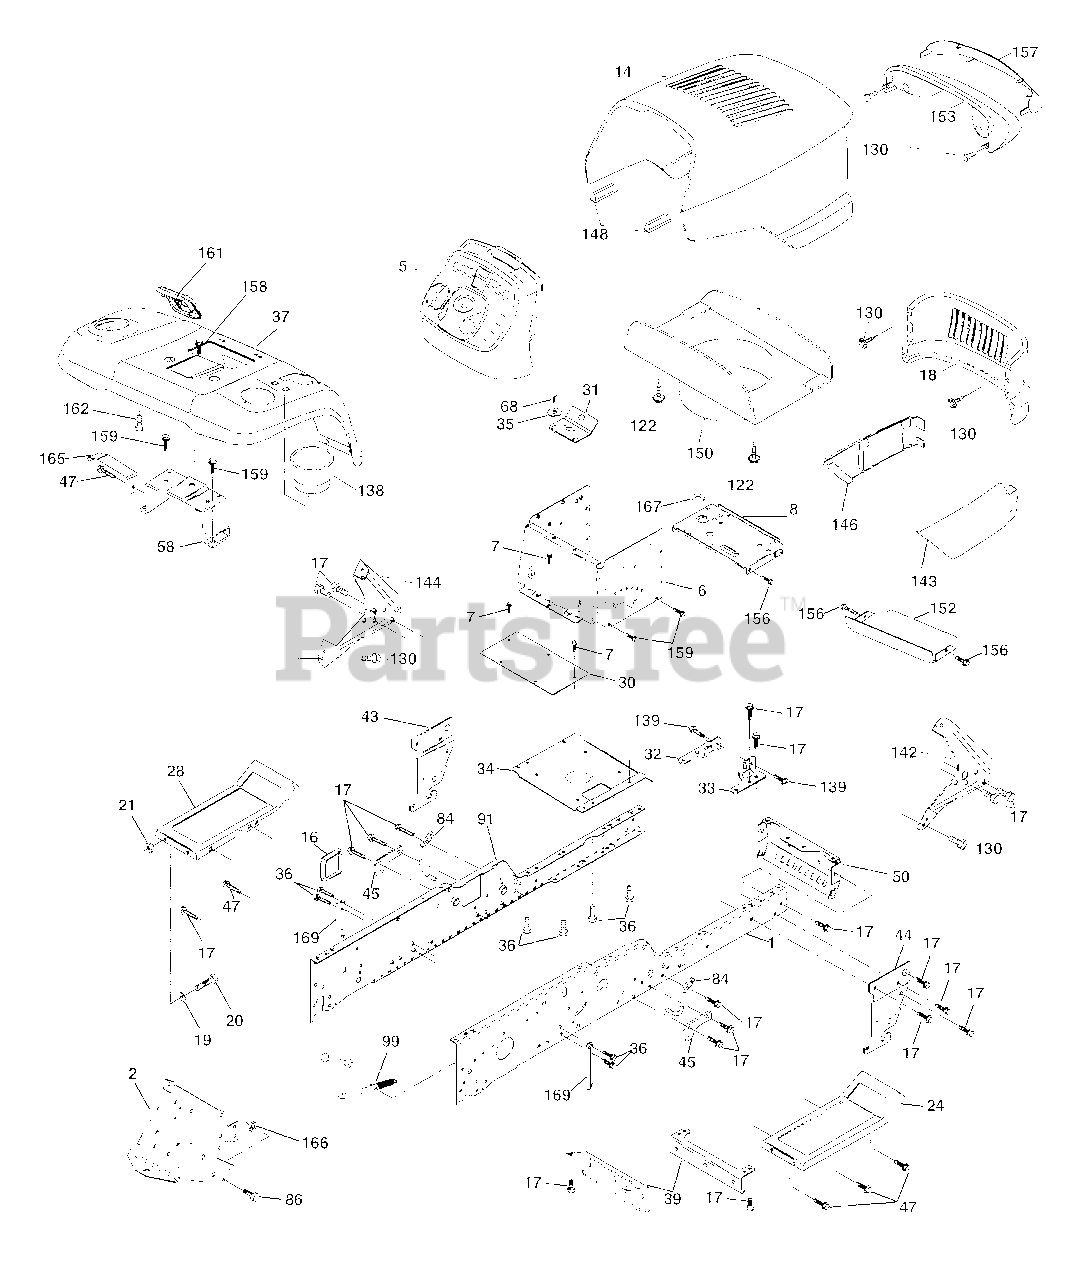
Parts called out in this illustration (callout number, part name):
1	Rail, Frame RH
2	Drawbar, Gt
5	Dash
6	Dash Asm., Lower
7	Screw, Thd Cut 1/4-20 x 1/2
8	Support, Battery
14	Hood Asm., Pnt
16	Cover, Access
17	Screw, 3/8-16 x 3/4
18	Grille
19	Washer 13/32 x 13/16 x 12 Ga.
20	Bolt, Fin Hex 3/8-16 x 1
21	Nut, Lock Hex w/Ins. 3/8-16 unc
24	Footrest, RH
28	Footrest, LH
30	Saddle, Hydro 1995
31	Bracket, Supt 1-pc VGT Steering
32	Bracket, Pivot Chassis LH
33	Bracket, Pivot Chassis RH
34	Plate Asm. Engine Chassis
35	Washer 11/32 x 11/16 x 16 Ga.
36	Screw 5/16-18 x 3/4
39	Bracket, Axle Front
43	Bracket, Spnsn Front Lh
44	Bracket, Spnsn Front Rh
45	Bracket Asm., Susp Chassis
47	Screw Thdrol 3/8-16 x 1/2 TYT
50	Bracket, Chassis Front
58	Bracket Asm., Fender
68	Screw, Thd 5/16-18 x 1/2
84	Upstop
86	Bolt, Fin Hex 7/16-14 unc x 1-1/4 Gr. 5
91	Rail, Frame Lh
99	Rod By Pass
122	Screw Hex Wshd 8-18 x 7/8
130	Screw HWHD Hi-Lo #13-16 x 3/4
138	Cupholder YTGT
139	Bolt Shoulder 5/16-18 TT
142	Bracket Dash RH
143	Skirt Grill RH
144	Bracket Dash LH
146	Skirt Grill LH
148	Extrusion Bumper
150	Duct Heat Hood
152	Shield Browning
153	Light Box Asm. w/Lens
156	Screw 5/16-18 x 3/4
157	Lens, Bar
158	Screw Thdrol 3/8-16 x 1/2
159	Screw 3/8-16 x 3/4
161	Console Fuel Window
162	Screw 1/4-1/2
165	Bracket Support Tank
166	Nut, Crownlock 7/16-14 unc
167	Bushing Snap
169	Bracket Chassis Sway
